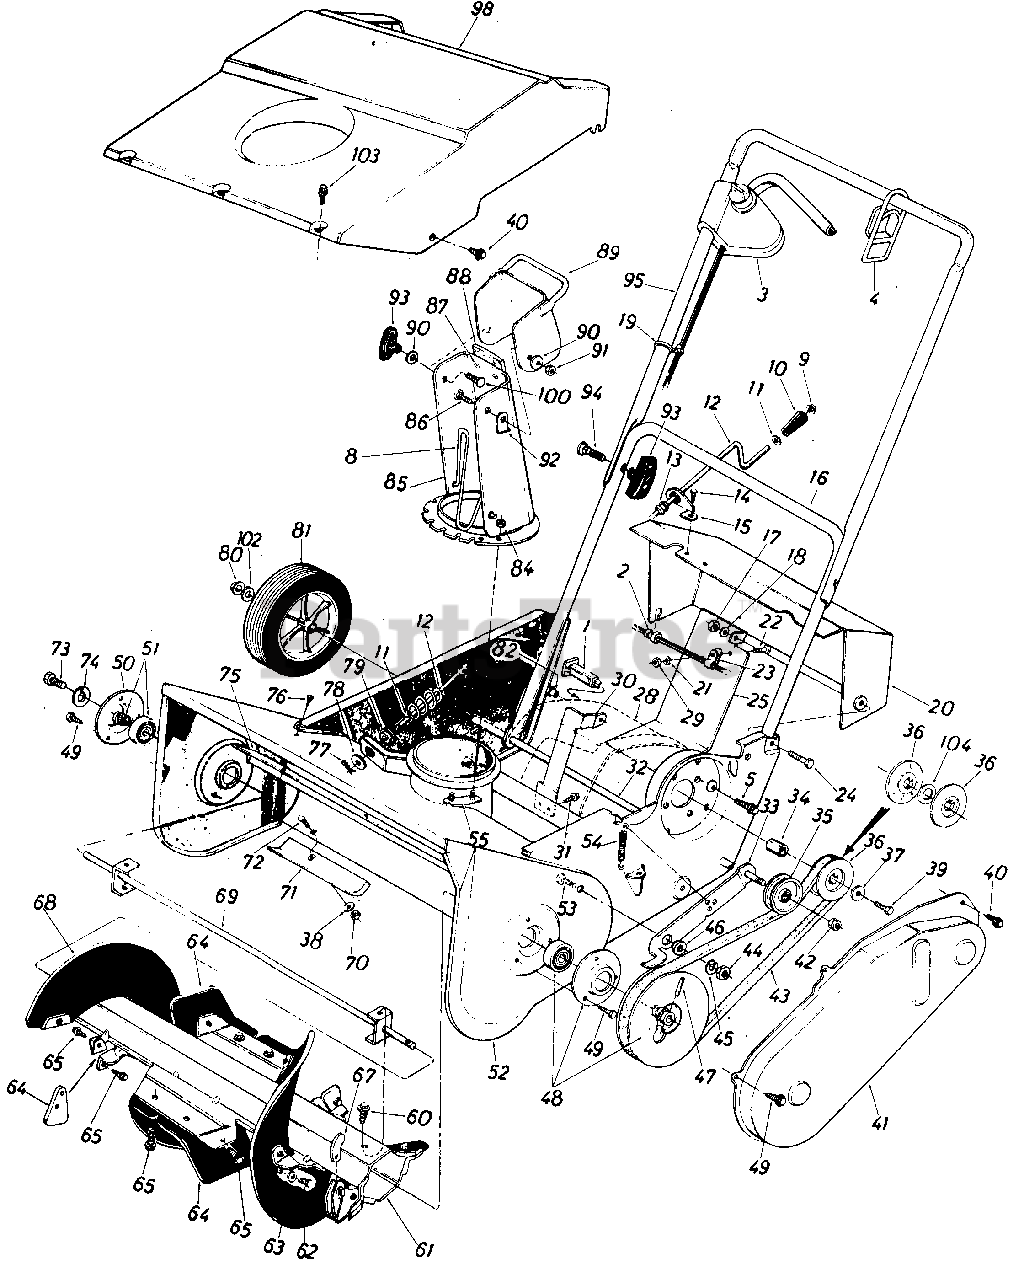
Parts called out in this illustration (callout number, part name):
1	Circuit Breaker 10 Amp
2	Cord Restraint
3	Control with Key
4	Restraint
5	Hex Bolt 5/16-18 x .50" Lg.*
8	Chute Guard
9	Push Nut 3/8 Rod
10	Knob Black 3/8 Dia. Hole
11	Fl-Wash. .385" I.D. x .62" O.D.
12	Chute Crank Ass'y.
13	Chute Crank Grommet
14	Hex Tap Scr. 114" x .75" Lg.
15	Upper Chute Crank Brk't.
16	Lower Handle
17	Hex Nut 5/16-18 Thd.*
18	L-Wash. 5/16" I.D.*
19	Cable Tie
20	Dash Panel Ass'y.
22	Truss Mach. Scr. #10-24 x .50" Lg.*
23	Cord Restraint
24	Hex Bolt 5/16-18 x 1.50" Lg.*
25	Snow Guard
28	Motor Shroud with Hardware
29	Hex Nut #10-24 Thd.*
30	Motor Support Brk't.
31	Hex L-Wash. Hd. AB Tap Scr. 1/4 x .62" Lg.
32	Wheel Axle
33	Idler Brake Brk't. Ass'y.
34	Spacer
35	Fl-Idler 2.00" x 1" w/Flange
36	3/8" V-Pulley .625" I.D. x 2.25
37	Bell-Wash. .345" I.D. x .88"
38	L-Wash. 1/4" I.D.*
39	Hex Scr. 5/16-24 x .75" Lg.*
40	Hex L-Wash. Hd. AB-Tap Scr. 1/4 x .62"
42	Hex L-Nut 3/8-24 Thd.
43	V-Belt 1/2" x 34" Lg.
44	Hex Nut 5/16-18 Thd.*
45	L-Wash. 5/16" I.D.*
46	Shld. Spacer 1.0" O.D. x .315 I.D.
47	Spring Pin Spir. 114" Dia. x 1.00" Lg.
48	Kit-Bearing, Cup and Pulley
49	Hex "B"-Tap Scr. 1/4-20 x .38" Lg.
52	Blower Housing Ass'y.
53	Truss Mach. Scr. 5/16-18 x .75" Lg.
54	Extension Spring .33" O.D. x 1.12" Lg.
55	Chute Flange Keeper Ass'y.
60	Hex L-Wash. Hd. AB-Tap Scr. 114 x .62" Lg.
61	Auger Half 21.0" Lg.
62	Hex Wash. Hd. Self-Tap Scr. 1/4-20 x .50" Lg.
63	Fl-Wash. .28" I.D. x .74" O.D.
64	Rubber Paddle Half
65	Hex B-Tap Scr. 1/4 x .62" Lg.
67	Small Counterweight
68	8.5" Dia. Rubber Spiral
69	Auger Axle Ass'y.
70	Hex Nut 1/4-20 Thd.
71	Shave Rail
72	Carriage Bolt 1/4-20 x .75"
73	Hex Wash. TT-Tap Scr. 1/4-20 x .75" Lg.
74	L-Wash. 1/4" I.D.
75	Thrower Housing Angle
76	Hex "B"-Tap Scr. 114" x .38" Lg.
77	Cotter Pin 3132" Dia. x .75"
78	Fl-Wash. .385" I.D. x 1.5" O.D.
79	Hex Bushing .385" I.D.
80	Cap Speed Nut 1/2" Rod
81	Wheel Ass'y. 6 x 1.50
84	Hex L-Nut 1/4-20 Thd.
85	5.0" Dia. Chute Ass'y.
86	Carriage Bolt 5/16-18 x .62"
87	Rivet.250" x .44" Lg.
88	Chute Seal
89	Top Chute Ass'y.
90	Bell-Wash. .345" I.D. x .88"
91	Hex Cent. L-Nut 5/16-18 Thd.
92	Top Chute Stop
93	Knob-Handle Ass'y.
94	Curved Hd. Carriage Bolt 5/16-18 x 1.75" Lg.
95	Upper Handle
98	Shroud
100	Carriage Bolt 5/16-18 x 1.00"
102	Fl-Wash. .75" O.D. x .50" I.D.
103	Hex AB-Tap Scr. #10 x .50"
104	Fl-Wash. .635" I.D. x .93" O.D.
